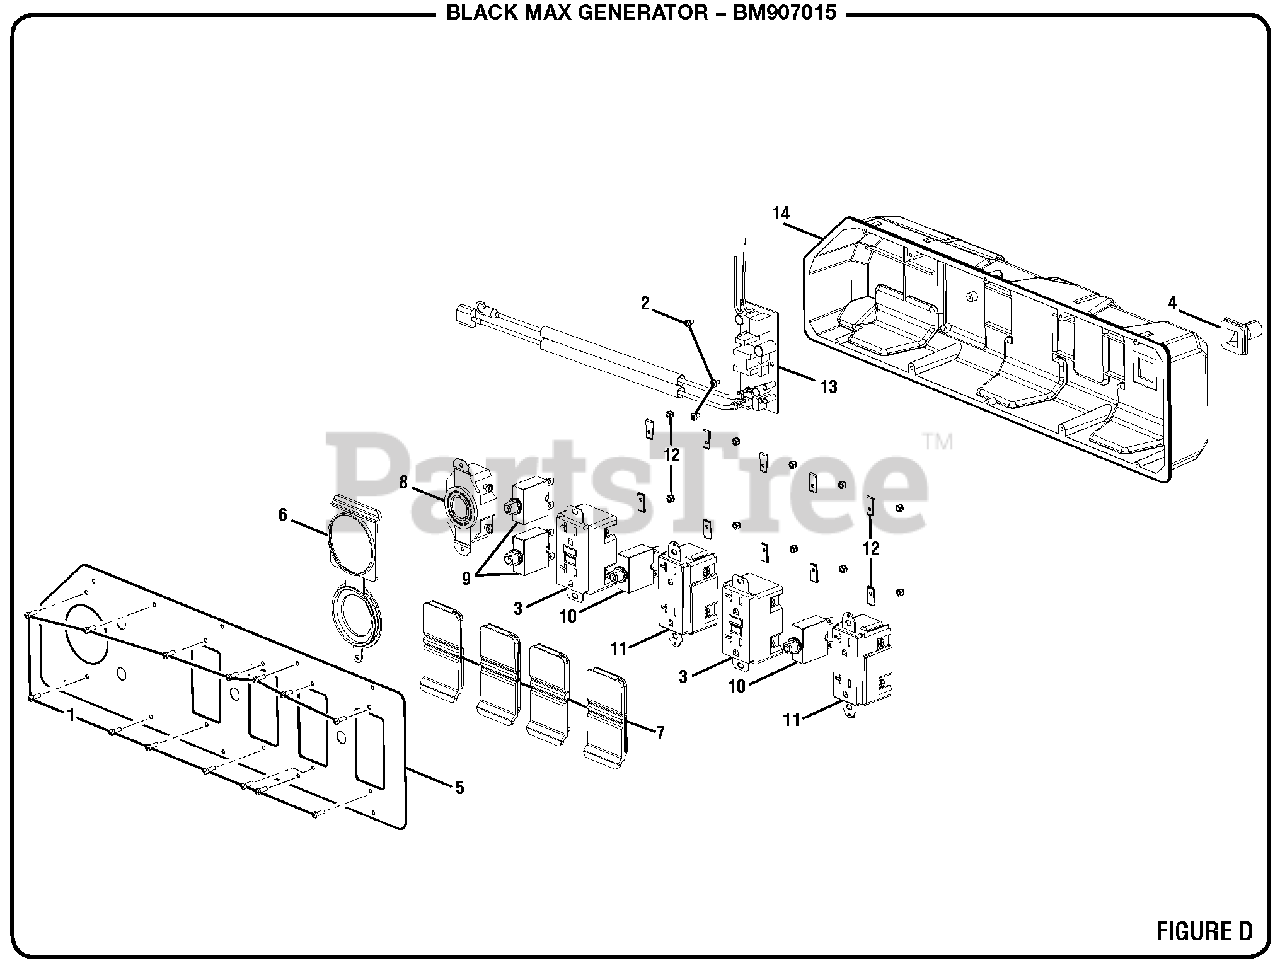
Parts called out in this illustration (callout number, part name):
1	Screw (6-20 x 3/8 in., Pan Hd.)
2	Screw (M3 x 5 mm, T10 Torx Pan Hd.)
3	120V GFCI Duplex Receptacle
4	Wire Protector
5	Control Panel Faceplate
6	Twist Lock Receptacle Cover
7	120V Duplex Receptacle Cover
8	120/240V Receptacle (30A)
9	Circuit Breaker (30A)
10	Circuit Breaker (20A)
11	120V Duplex Receptacle
12	Hex Lock Nut (6-32)
13	Battery Charger
14	Control Box
